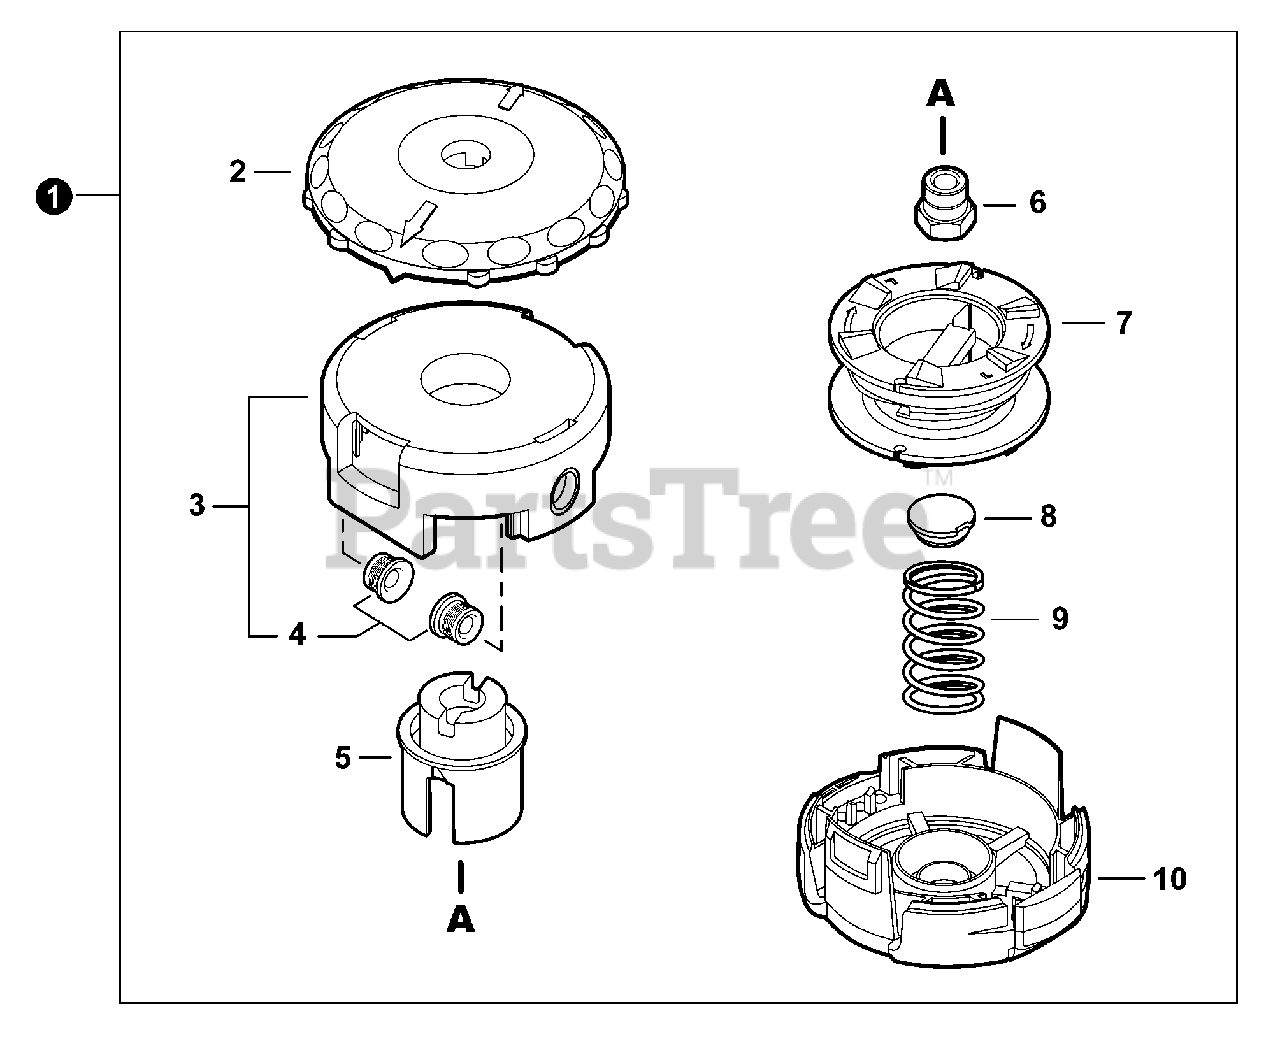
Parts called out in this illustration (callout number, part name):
1	TRIMMER HEAD, SPEED-FEED® 400
3	HOUSING ASSY, SPOOL
5	HUB (RH) WHITE
6	BUSHING 3/8"-24 RH BLACK
8	CAP, SPRING
9	SPRING, GOLD
10	COVER, SPOOL
